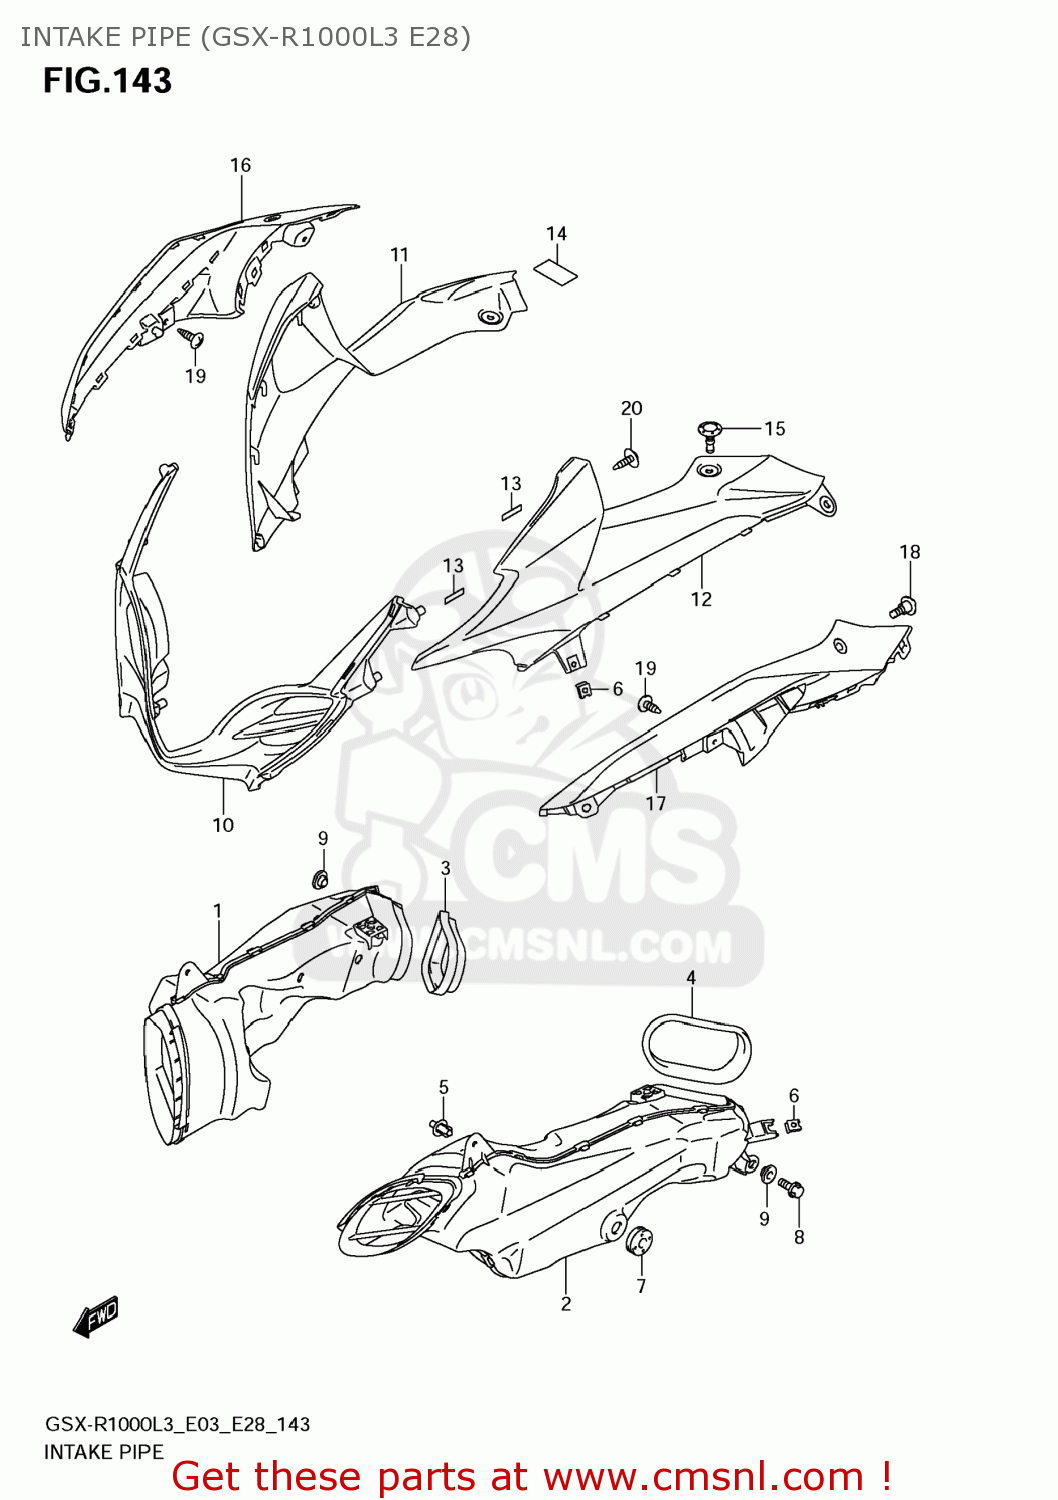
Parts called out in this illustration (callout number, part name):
1	PIPE,AIR INTAKE,R
2	PIPE,AIR INTAKE,L
3	MOLDING,AIR INTAKE,R
4	MOLDING,AIR INTAKE,L
5	CLIP(BLACK)
6	NUT
7	CUSHION
8	BOLT
9	WASHER
10	COVER,INTAKE
11	COVER,INTAKE,R
12	COVER,INTAKE,L
13	TAPE(6X25X0.13)
14	PROTECTOR(30X80X1)
15	CLIP
16	COWLING,SIDE UPR,R
17	COWLING,SIDE UPR,L
18	SCREW(5X16)
19	SCREW
20	SCREW(5X12)
